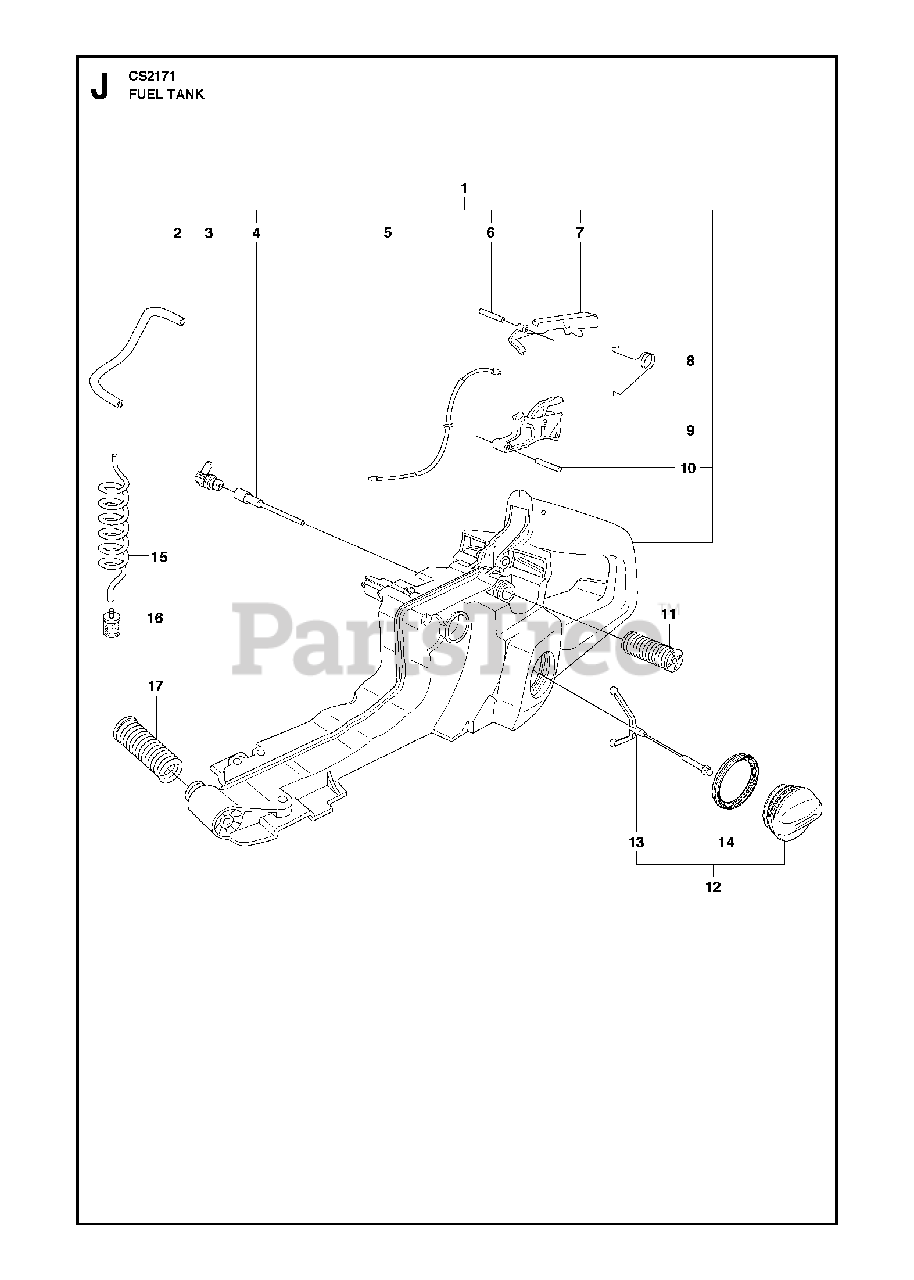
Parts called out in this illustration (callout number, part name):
1	TANK
2	HOSE
3	CONNECTOR
4	TANK VALVE
5	WIRE
6	PIN 3X25
7	THROTTLE LOCK
8	SPRING
9	THROTTLE TRIGGER
10	PIN CPH8 4X20
11	ANTIVIBE MOUNT
12	TANK CAP
13	HOLDER
14	SEALING
15	FUEL HOSE
16	FUEL FILTER
17	ANTIVIBE MOUNT
17	AV SPRING (HARD)
